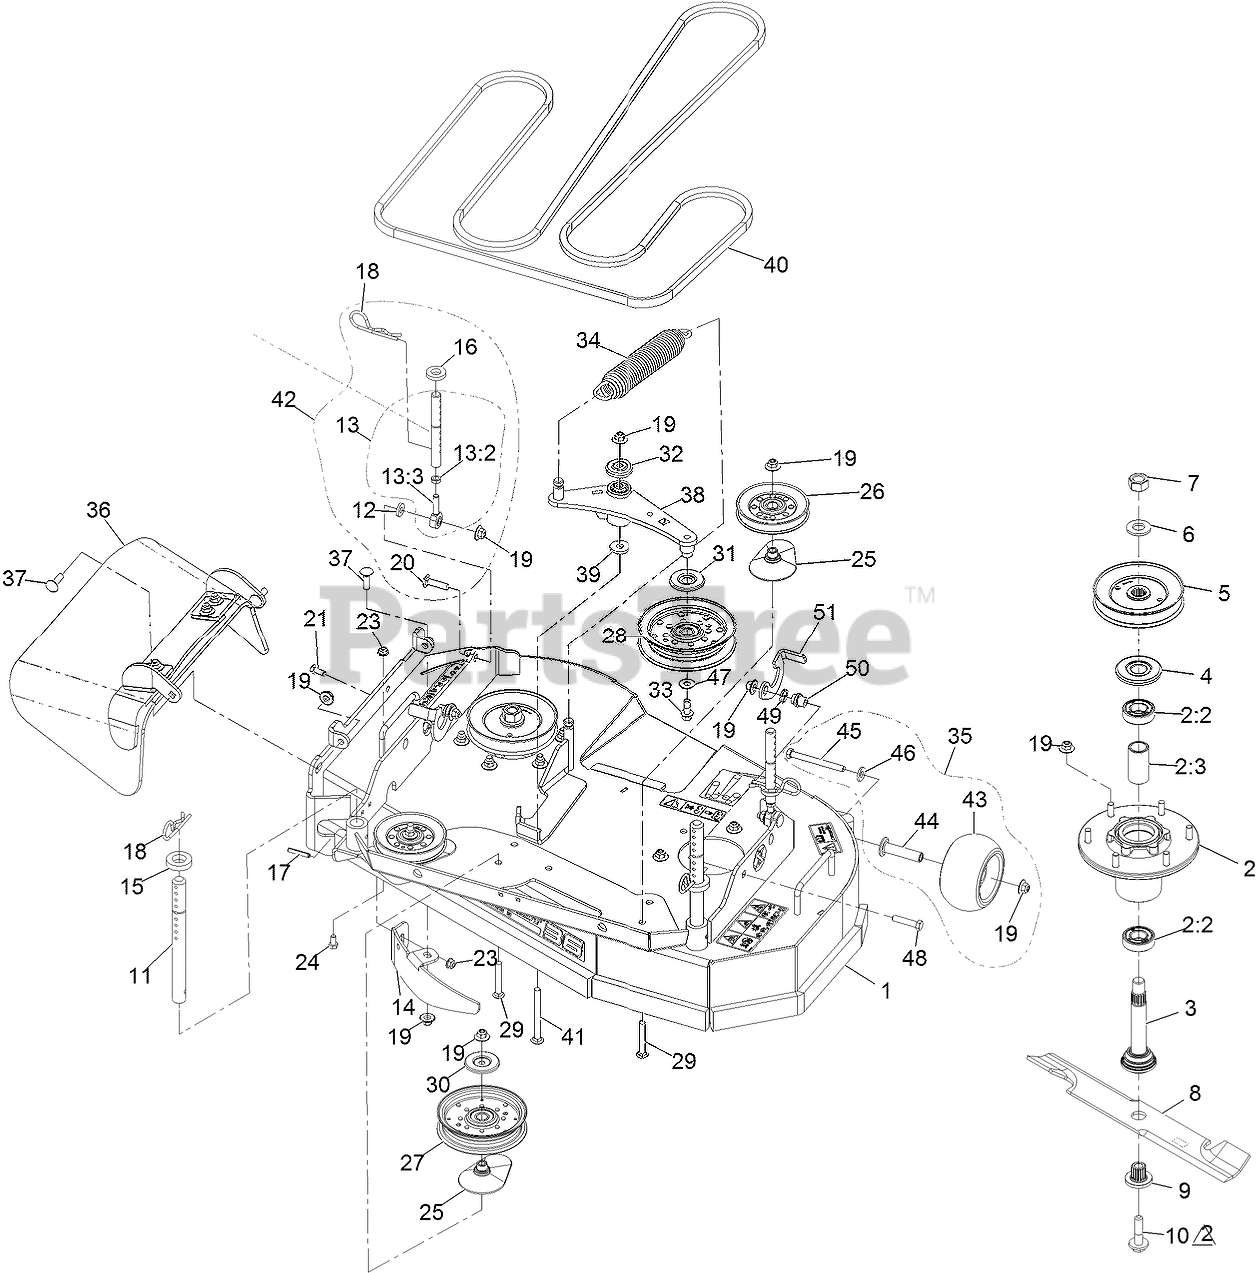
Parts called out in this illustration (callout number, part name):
1	ASM-Deck Decals 36
2	ASM-CUTTER HSG WITH BEARINGS
2:2	BEARING-BALL
2:3	SPACER-BEARING
3	ASM-SPINDLE AND SEAL
4	GUARD,BEARING TOP .989
5	SHEAVE-BLADE DRIVE
7	NUT-HEX
9	BUSHING,SPLINED
10	SCREW,SEMS 1/2-20 X 2.19
11	ROD, DECK SUPPORT
13	ASM, Support Link
13:2	BALLJOINT
13:3	NUT-HJ
14	BAFFLE, DOGLEG
15	SPACER-DECK SUPPORT
18	PIN-CUT HEIGHT
19	Nut-Nyloc 3/8-16 Flg
20	SCREW-CARR
21	SCREW-HH
23	NUT-HF, NI
24	SCREW-HH
25	SPACER-PULLEY
26	Idler - V 4.13 Eod-A
27	PULLEY-IDLER, FLAT
28	IDLER-PULLEY, FLAT
29	SCREW-CARR
30	SHIELD-DUST
31	SHIELD-GUARD, DUST
32	GUARD-TOP
33	SCREW-HFH
34	SPRING-EXTENSION
35	KIT-ANTISCALP ROLLER
36	Rubber Deflector ASM
37	BOLT-CARR
38	ASM.-Arm, Idler
40	BELT-V
41	SCREW-CARR
42	Kit-Support Link Svc
43	ROLLER-SCALP, ANTI
44	AXLE, ROLLER
45	SCREW-HH 3/8-16 X 3 3/4 GR 8
46	WASHER-BELLEVILLE
47	WASHER-FLAT
48	SCREW-HH
49	WASHER-SPRING
50	Bushing-Latch
51	Latch - Deck
